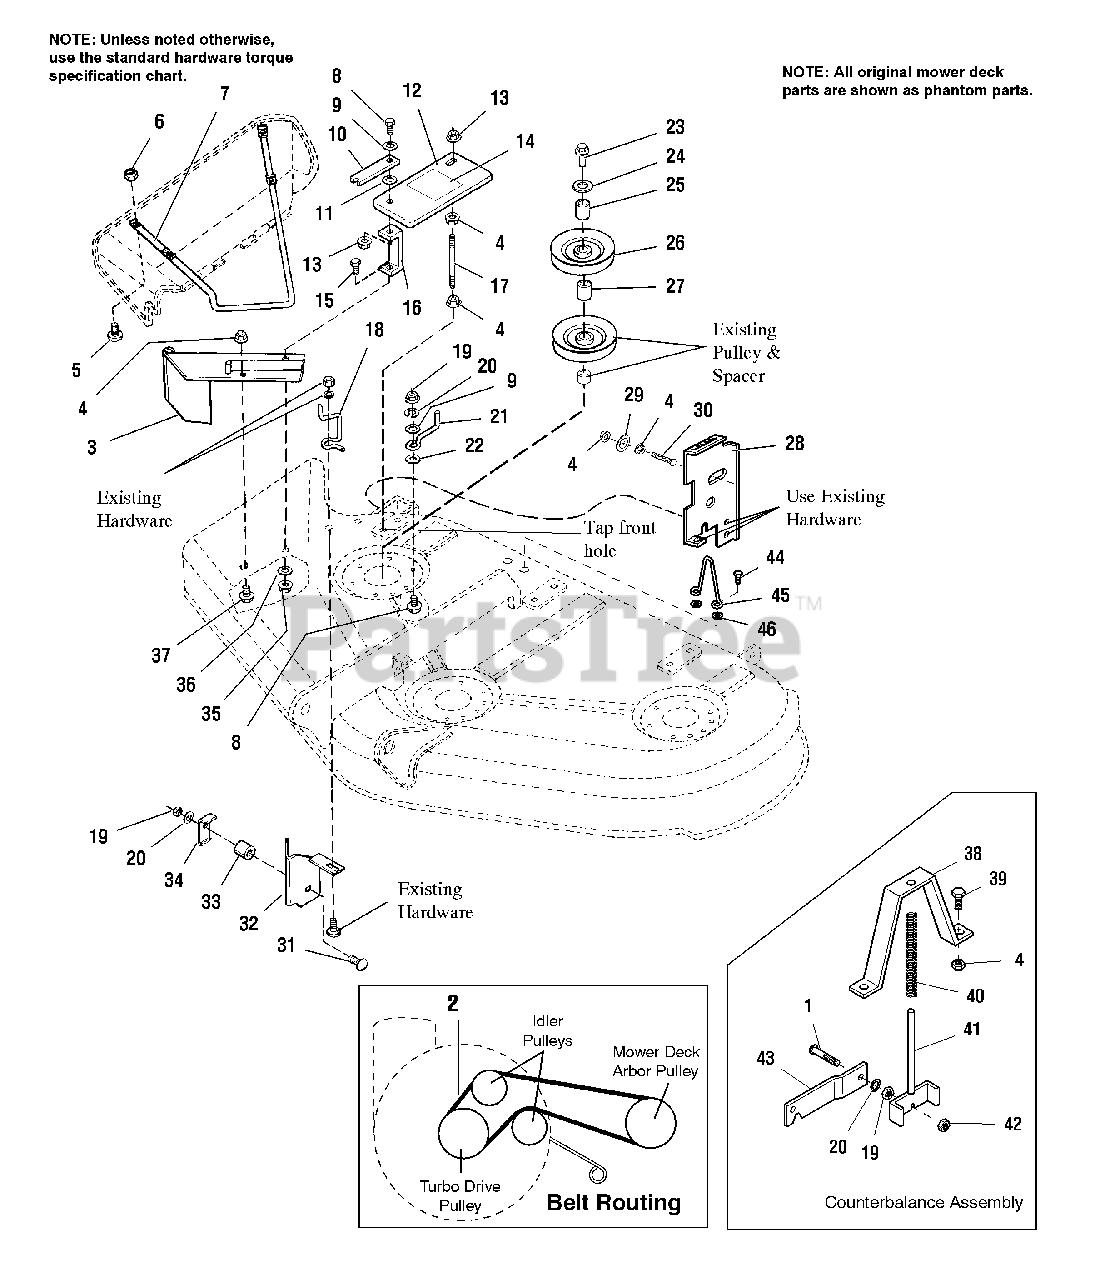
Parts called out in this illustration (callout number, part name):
1	CARRIAGE BOLT, 5/16-18 x 1-1/4
3	PIVOT ASSEMBLY
4	NUT, Hex Flange, Whizlock, 5/16-18
5	CAPSCREW, Truss Head, #10-24 x 3/4" Lg.
6	NUT, Nylock, #10-24
7	ROD, Deflector
8	CAPSCREW, Hex Hd., 5/16-18 x 1" Lg.
9	WASHER, Flat, 11/32
10	SUPPORT STRAP, Deflector
11	WASHER, Nylon, 0.388" Dia.
12	COVER, Turbo Belt
13	NUT, Hex, Nylock, 5/16-18
14	DECAL, Warning
15	CAPSCREW, Hex Hd., 5/16-18 x 1" Lg.
16	SUPPORT, Belt Cover
17	STUD, 5/16-18 x 5-3/4" Lg.
18	LATCH, Spring Wire
19	NUT, Hex, 5/16-18
20	LOCKWASHER, 5/16
22	WASHER, Flat, 3/8
23	NUT, Sleeve
24	WASHER, Belleville
27	HUB, Double, .610" Long
28	BRACKET, Height Adjustment
29	CUP WASHER
30	CAPSCREW, Rnd Hd., 5/16-18 x 2.5 Lg.
31	CARRIAGE BOLT, 5/16-18 x 1-1/4" Lg.
32	BRACKET ASSEMBLY
34	BRACKET, "L"
35	NUT, Hex Flange, Whiz-Lock, 5/16-18
36	WASHER, Flat, 13/32
37	CARRIAGE BOLT, 5/16-18 x 3/4" Lg.
38	BRACKET, Counterbalance
39	SCREW, Hex Whiz-Lock, 5/16-18 x 3/4
40	SPRING, Compression
41	ROD ASSEMBLY, Counterbalance
42	NUT, Flange, 2-Way Lock, 5/16-18
44	CAPSCREW, Taptite, 5/16 x 1
46	WASHER, 5/16
